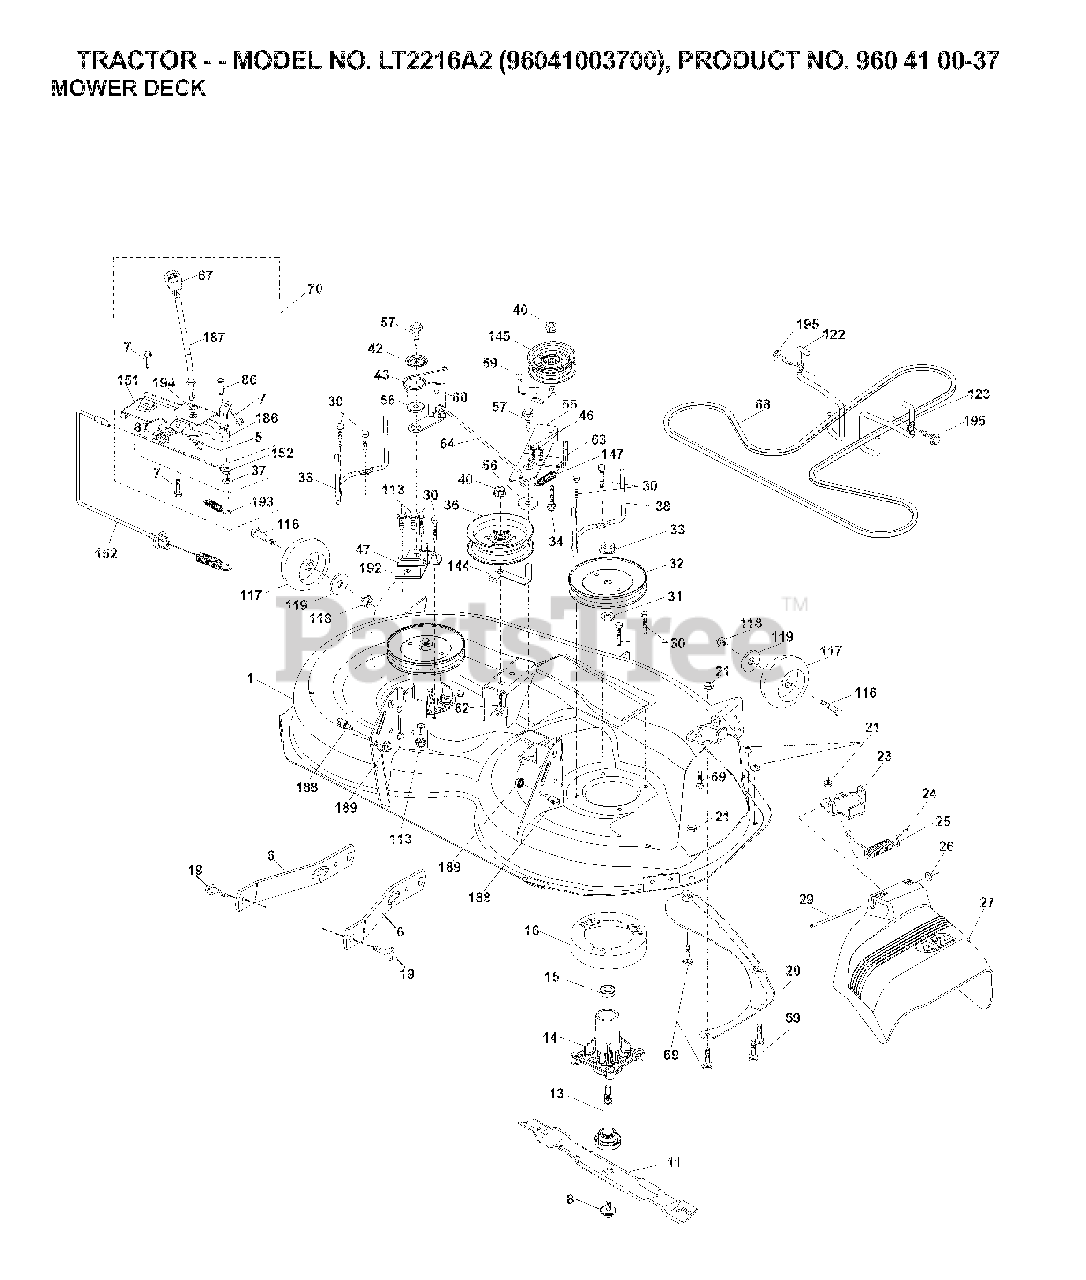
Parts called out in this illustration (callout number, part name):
1	DECK.WELDMENT.42"
6	ARM.SUSPENSION.MOWER.R
7	SCREW.#10 X 0.750.BOS THREAD
8	BOLT.WASHER.ASM.7/16-2
11	42" HI-LIFT BLADE
13	SHAFT.ASM.MDRL.N/GREASE.38
14	HOUSING MANDREL
16	STRIPPER, MWR ROUND
19	BOLT.SHOULDER
20	BAFFLE.VORTEX
21	LOCKNUT
23	BRKT.DEFLECTOR.38"2005+
24	CAP-SLEEVE LT
25	SPRING.TORSION.DEFLECT
26	NUT PUSH M
27	SHIELD.DEFLECTOR.MOWER.42"BLAC
29	ROD.HINGE
30	SCREW, WASHER HEAD
31	WASHER.SPACER.MANDREL
32	PULLEY.MANDREL.5.438.PD
33	NUT.FLANGE.LOCK.TOP
34	BOLT.3/8-16X1.50
36	PULLEY.IDLER.48"PRIMARY
38	KEEPER.BELT.LH.MANDREL
40	NUT LOCK FLG 3/8-16 UNC
42	SPRING.TORSION.BRAKE
43	SRPING.TORSION.RETAINE
46	SCREW.1/4-20X5/8
47	BRKT.CLUTCH.CABLE
55	IDLER.ARM
56	SPACER.RETAINER
57	SCREW 3/8-16X1
59	GUARD, BELT
60	ARM BRAKE MOWER
62	BOLT
63	ARM BRAKE MOWER
64	LINK BRAKE
67	HANDLE.CLUTCH.CABLE.LT
68	BELT.DRIVE.MOWER.TEX.42"
69	BOLT
70	CLUTCH.ASM.MANUAL.LT.TEX
113	BOLT.5/16HEX.WHS.HD
117	WHEEL.GAGE.HALF.SPOKED
118	LOCKNUT
119	WASHER
122	KEEPER BELT ENGINE LH
123	KEEPER BELT RH
144	KEEPER.BELT.MOWER
145	PULLEY.IDLER.2006
147	RETURN SPRING
152	CLUTCH CABLE
188	STUD.FASTNER.W/ANTI-ROTATE
189	NUT LOCK HEX FLANGE 5/16-18
192	BRKT.BRAKE.STAND.LH.
195	SCREW, 3/8-16X3/4
